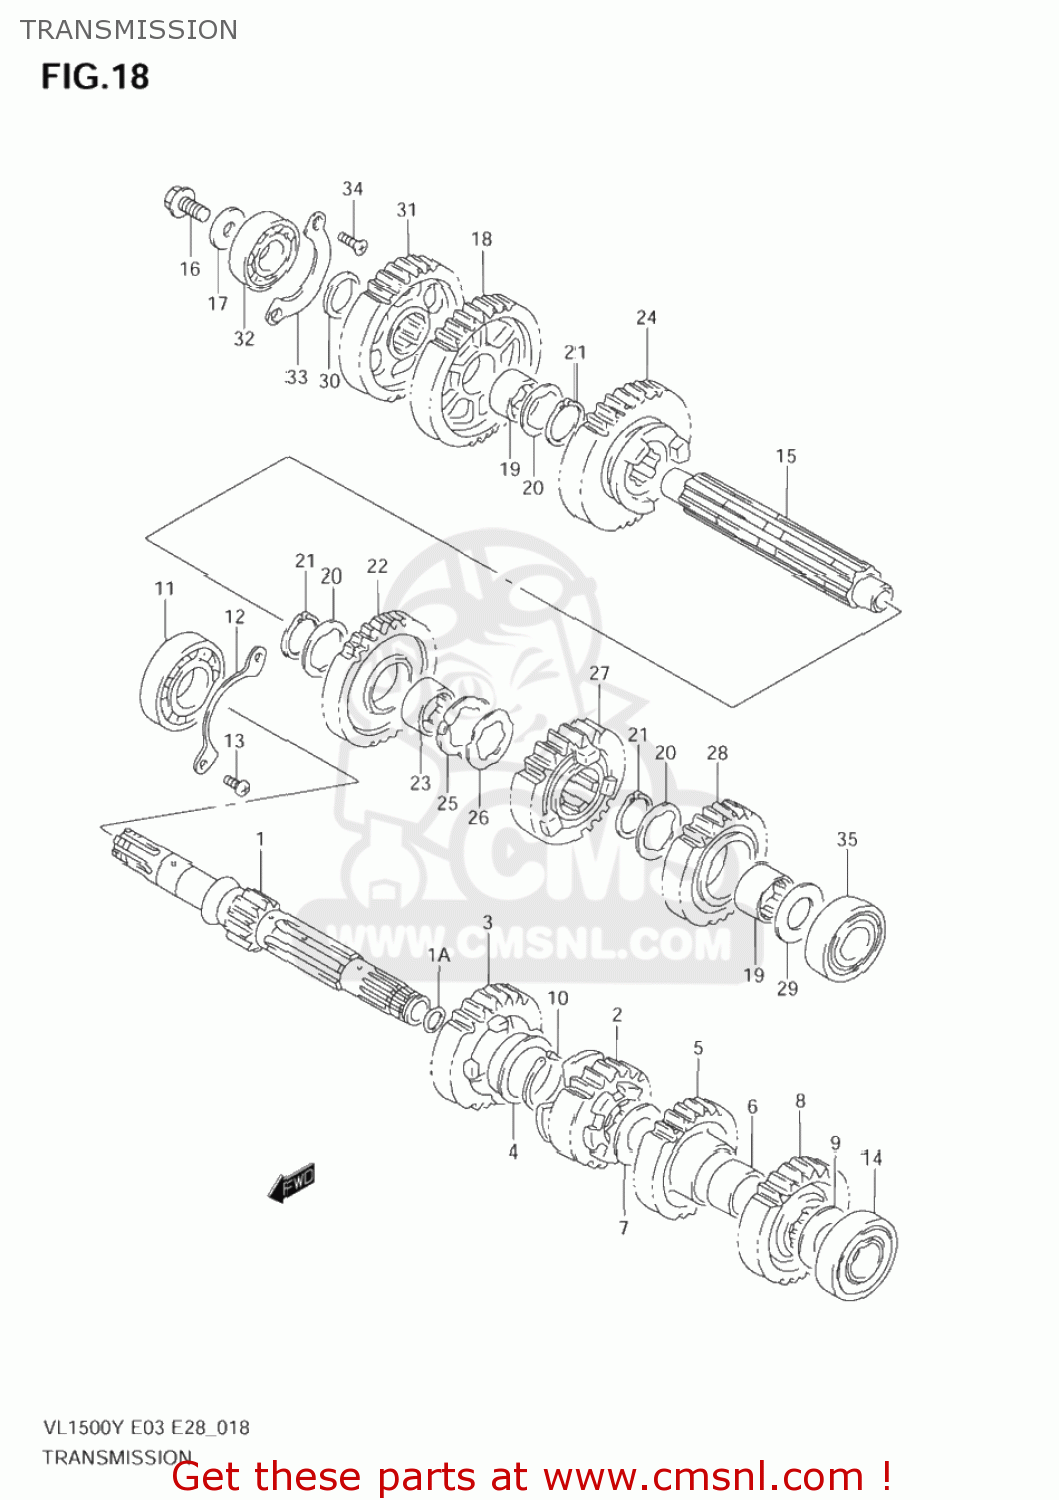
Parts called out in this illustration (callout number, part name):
1	SHAFT,COUNTER(NT:12)
1A	O RING(D:1.9,ID:16.6)
2	GEAR,2ND DRIVE(NT:17)
3	GEAR,3RD DRIVE(NT:21)
4	BUSH(28X32X2)
5	GEAR,4TH DRIVE(NT:24)
6	BUSH,4TH DRIVE GEAR
7	SHIM(22X32X1)
8	GEAR,5TH DRIVE(NT:26)
9	SHIM(20X32X1)
10	CIRCLIP
11	BEARING(25X62X17)
12	RETAINER,CNTR SHAFT BEARING
13	SCREW
14	BEARING(20X52X15)
15	SHAFT,DRIVE
16	BOLT(10X24)
17	WASHER
18	GEAR,1ST DRIVEN(NT:36)
19	BUSH
20	WASHER,LOCK
21	CIRCLIP
22	GEAR,2ND DRIVEN(NT:31)
23	BUSH,3RD DRIVEN GEAR
24	GEAR,3RD DRIVEN(NT:28)
25	WASHER
26	WASHER,LOCK
27	GEAR,4TH DRIVEN(NT:25)
28	GEAR,5TH DRIVEN(NT:23)
29	WASHER
30	WASHER(22X32X3)
31	GEAR,OVER DRIVING DRIVE(NT:34)
32	BEARING(22X56X16)
33	RETAINER,CNTR SHAFT BEARING
34	SCREW
35	BEARING(20X52X15)
